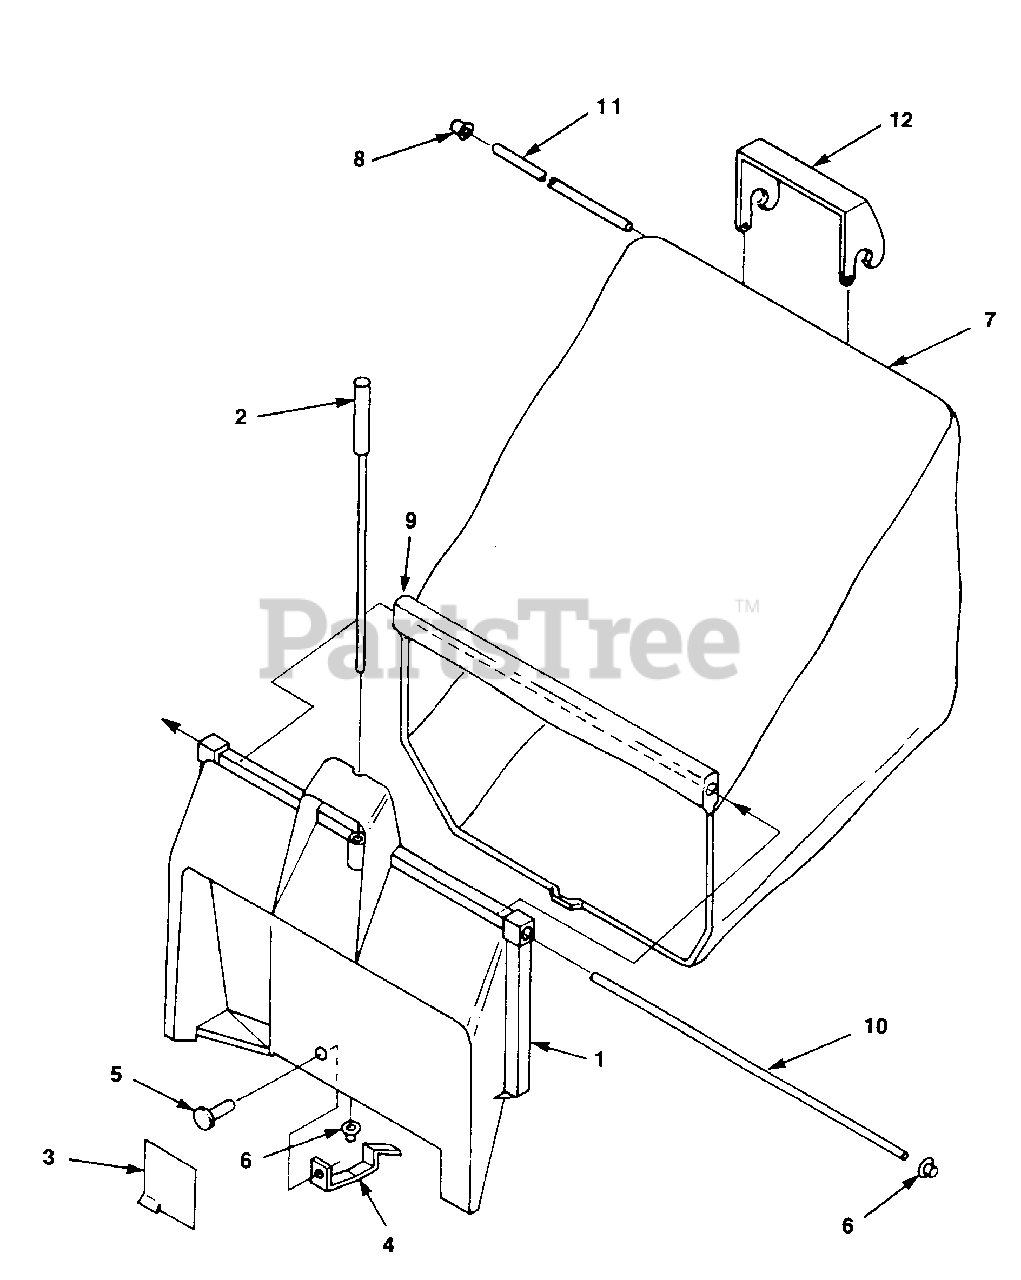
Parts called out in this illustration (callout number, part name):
1	ADAPTER ASSY.
2	ROD - Latch release
3	DEFLECTOR
5	RIVET 5/32 x 3/8"
6	NUT - Pal
7	BAG - Replacement
8	RETAINER - Bag rod
9	ROD - Bag support
10	ROD - Bag hinge
11	ROD - Bag
12	HANDLE-Bag
